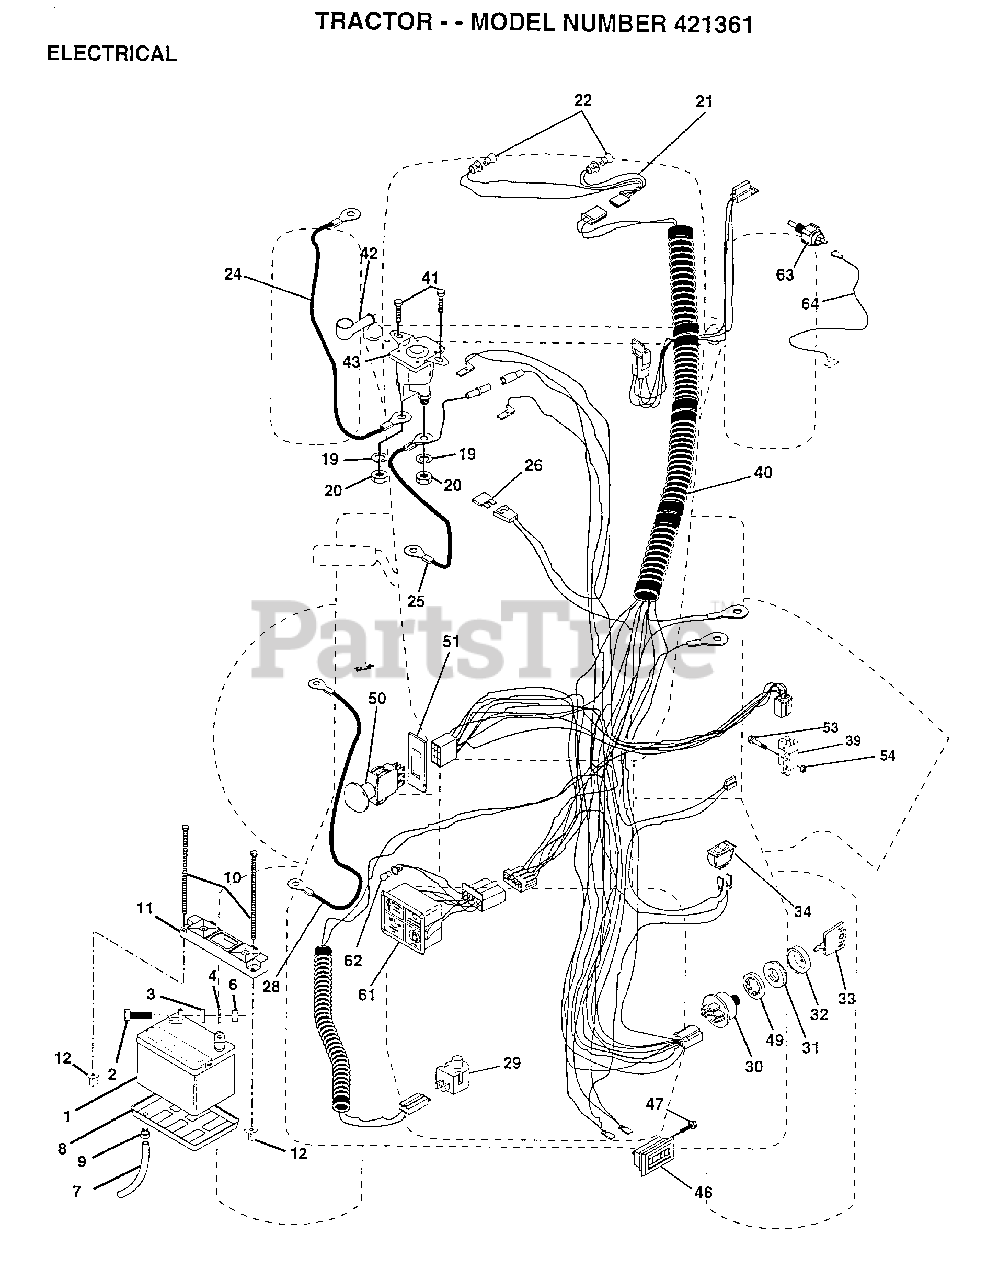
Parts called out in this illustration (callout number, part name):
2	BOLT LT
3	LOCKWASHER
4	WASHER
7	"DRAIN TU T, BATT"
8	"TRAY T, BATTERY"
9	HOSE CLAMP T
20	NUT
21	"HARNESS,LIGHT SOC"
22	HEADLAMP BULB
24	CABLE.BATY.22.RED
25	CABLE.BATRY.4GA.
26	FUSE HYT
28	CABLE.BATRY.4GA.
29	SWITCH SEAT
32	COVER KEY SWITCH
33	KEY MLD GEN DELTA
34	SWITCH LT
39	SWITCH INTERLOCKT
40	HARNESS.IGNITION
41	SCREW
46	HOUR METER T
47	SCREW
49	LOCKWASHER
51	RING RETAIN PTO
53	SCREW
54	"NUT,KEPS"
61	LIGHT.PKG.ASM.
62	BULB LIGHT T
